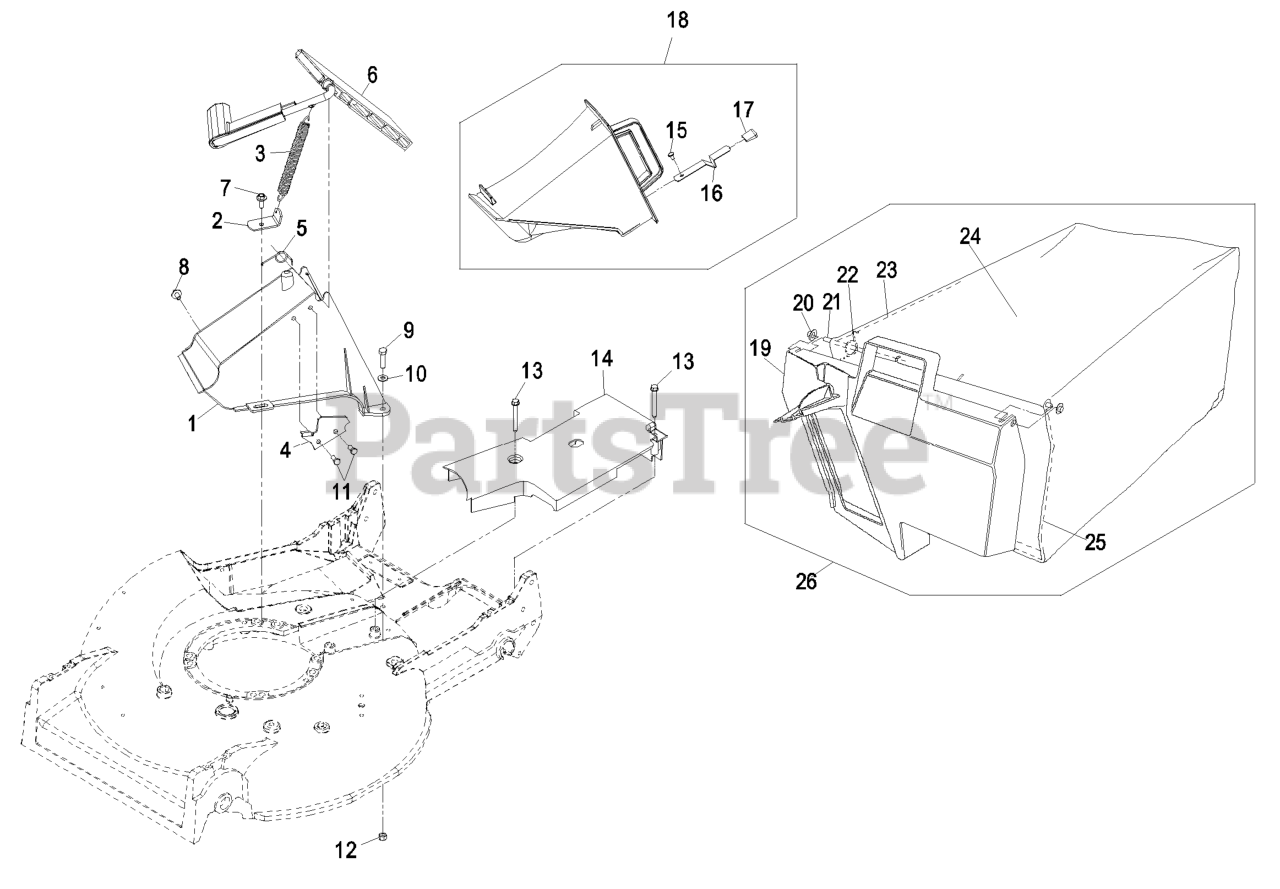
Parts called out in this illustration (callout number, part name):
1	TUNNEL-DISCHARGE
2	BRACKET-SPRING
3	SPRING-DOOR
4	LATCH-PLATE
5	RETAINER-DOOR
6	DISCHARGE DOOR ASM
7	SCREW-HWH
8	SCREW AND WASHER ASM
9	SCREW-HH
10	WASHER-FLAT
11	SCREW-PLASTITE
12	NUT-LOCK, NI
13	SCREW-HWH
14	COVER-BELT
15	RIVET-HEAD, FLAT
16	LATCH-PLUG, DISCHARGE
17	GRIP-LATCH
18	DISCHARGE PLUG ASM
20	NUT-PUSH
21	HINGE-DOOR, BAG
24	BAG, GRASS METRO21
25	FRAME-BAG
26	ASM,GRASS BAG
